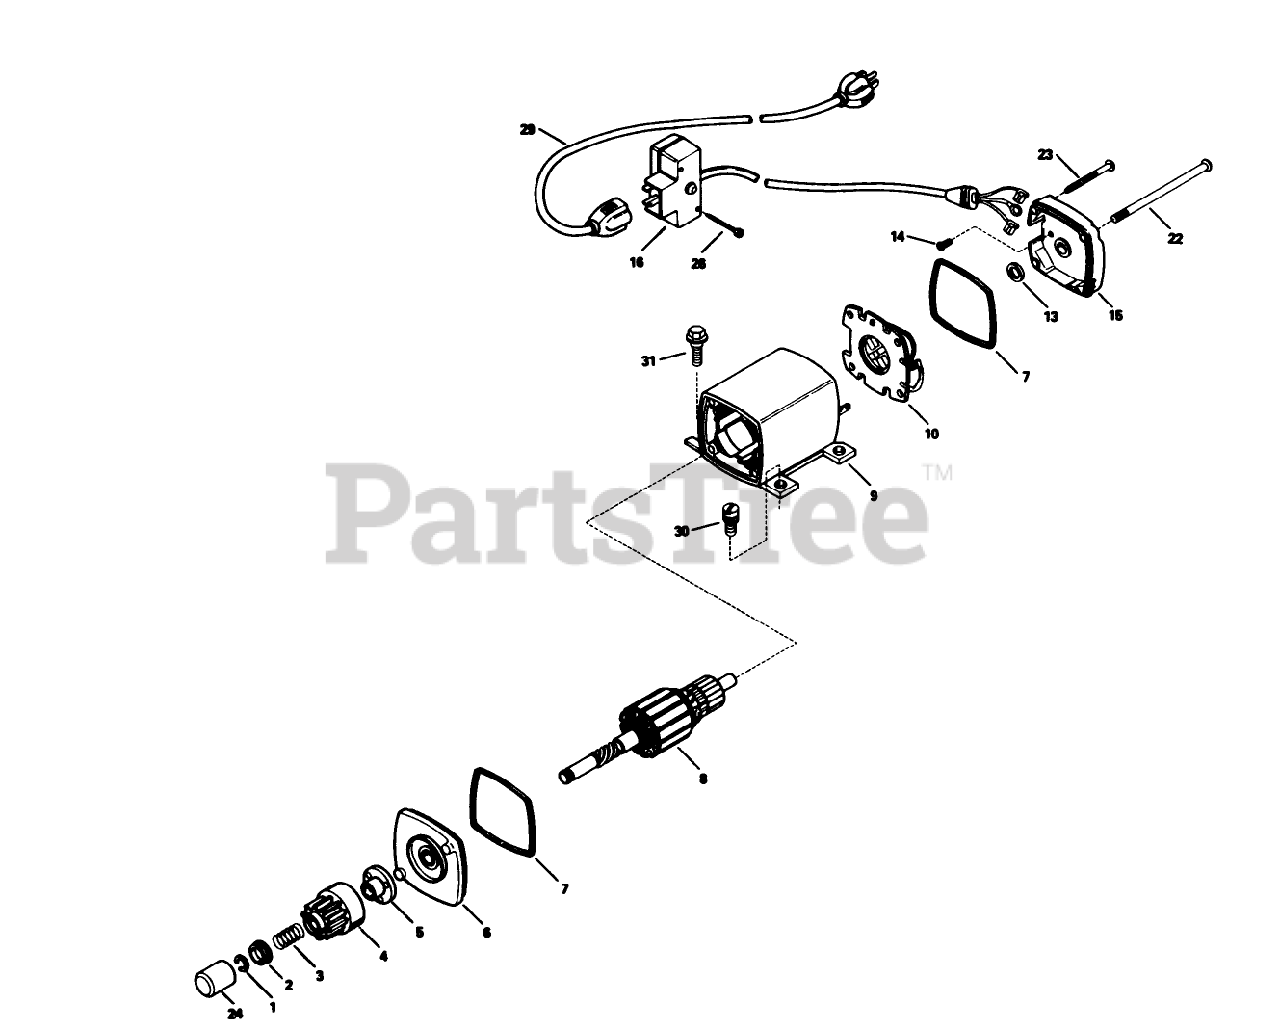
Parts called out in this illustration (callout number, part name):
1	Ring-Retainer
2	Retainer-Spring
3	Spring-Anti Drift
4	Gear
5	Nut-Engaging
6	Cap Assembly-Cap End (Incl. Ref. #7)
7	O-Ring
8	Armature
9	Housing Assy.
10	Card ASM
13	Washer-Thrust
14	Screw-Ground
15	Cap Assembly (Incl. Ref. #7)
16	Box Assembly-Switch (Incl. Ref. #26)
22	Bolt-Case
23	Screw-Ground
24	Cover-Dust
26	Screw
29	Cord-Extension
30	Screw
31	Screw (1/4-20x1/2)
